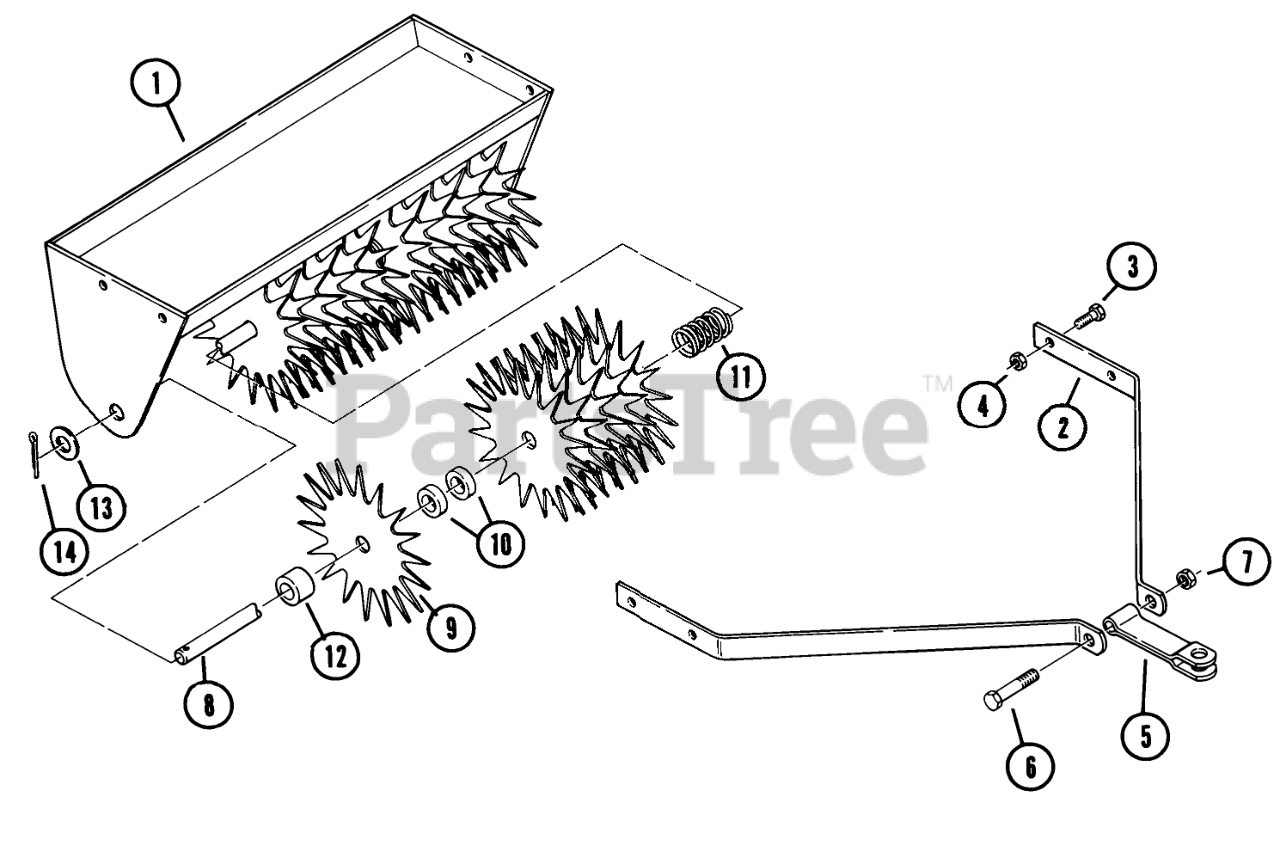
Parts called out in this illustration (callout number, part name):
1	Weight Tray Assembly
2	Side Bar
3	Bolt
4	Nut
5	Hitch Assembly
6	Bolt 1/2-13 x 3 1/2
7	Nut
9	Spike
10	Cup Spacer
11	Spring
12	BUSHING
13	Washer
14	Cotter Pin
